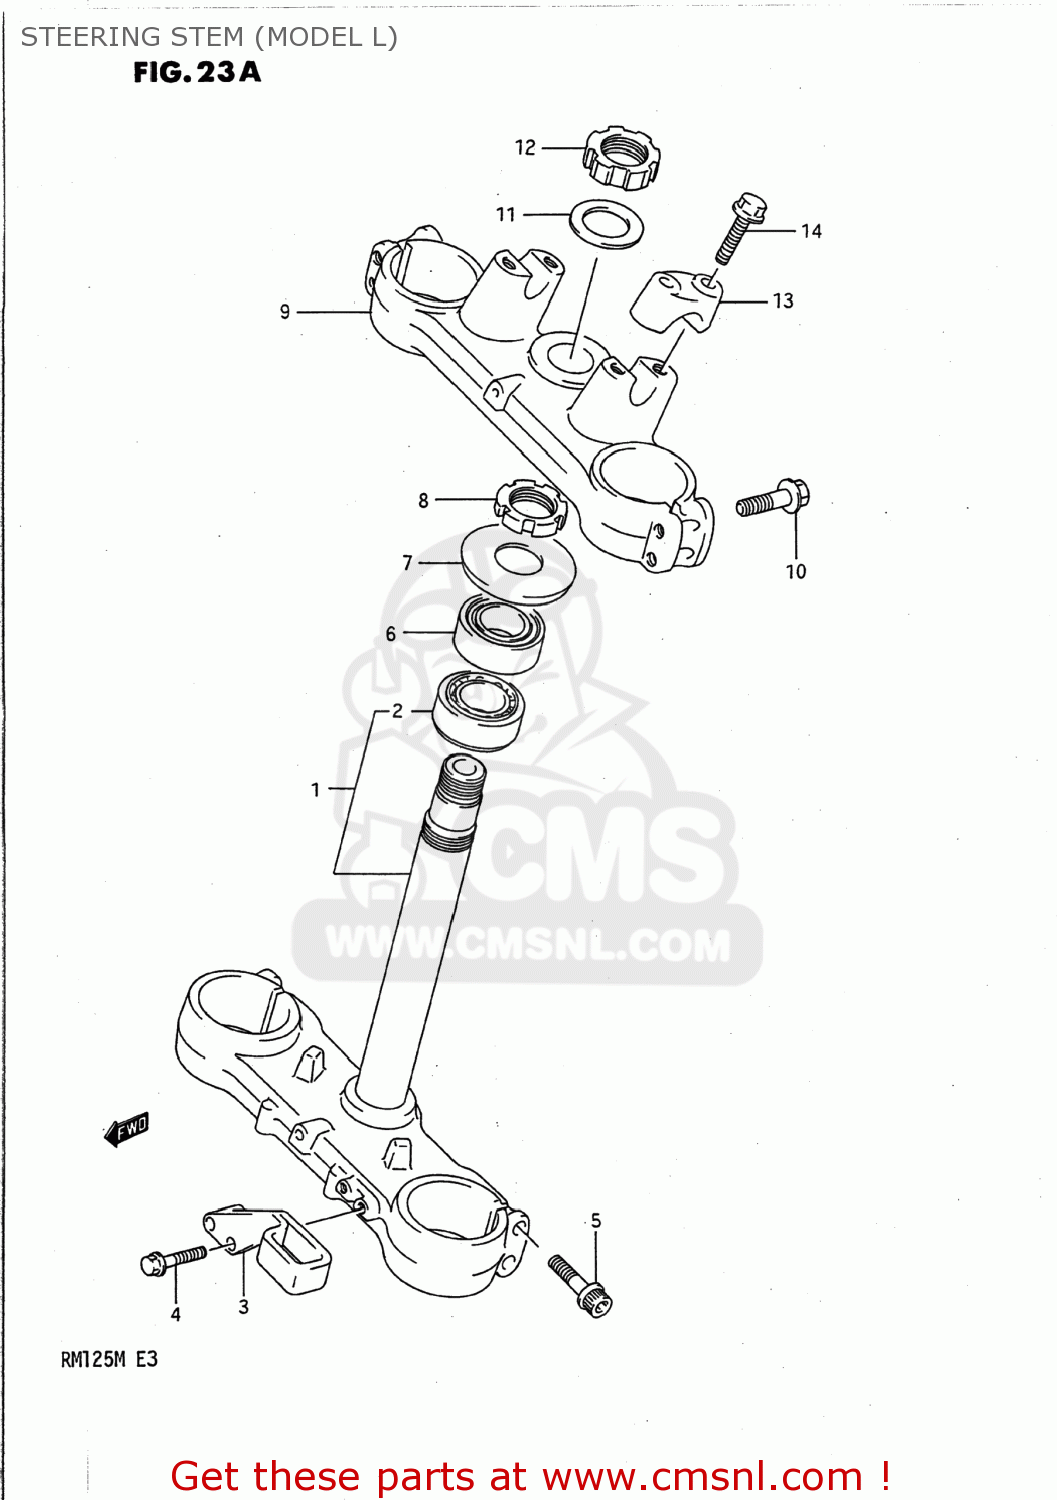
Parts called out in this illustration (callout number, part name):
1	STEM,STEERING
2	BEARING(28X54X16)
3	GUIDE,HOSE
4	BOLT
5	BOUT
6	BEARING
7	SEAL,STEERING,UPPER DUST
8	NUT,STEERING
9	HEAD,STEERING STEM
10	BOLT,STEM HEAD(8X40)
11	WASHER,STEERING STEM
12	NUT,STEM HEAD
13	HOLDER,HANDLEBAR
14	BOLT,HANDLE HOLDER(8X35)
